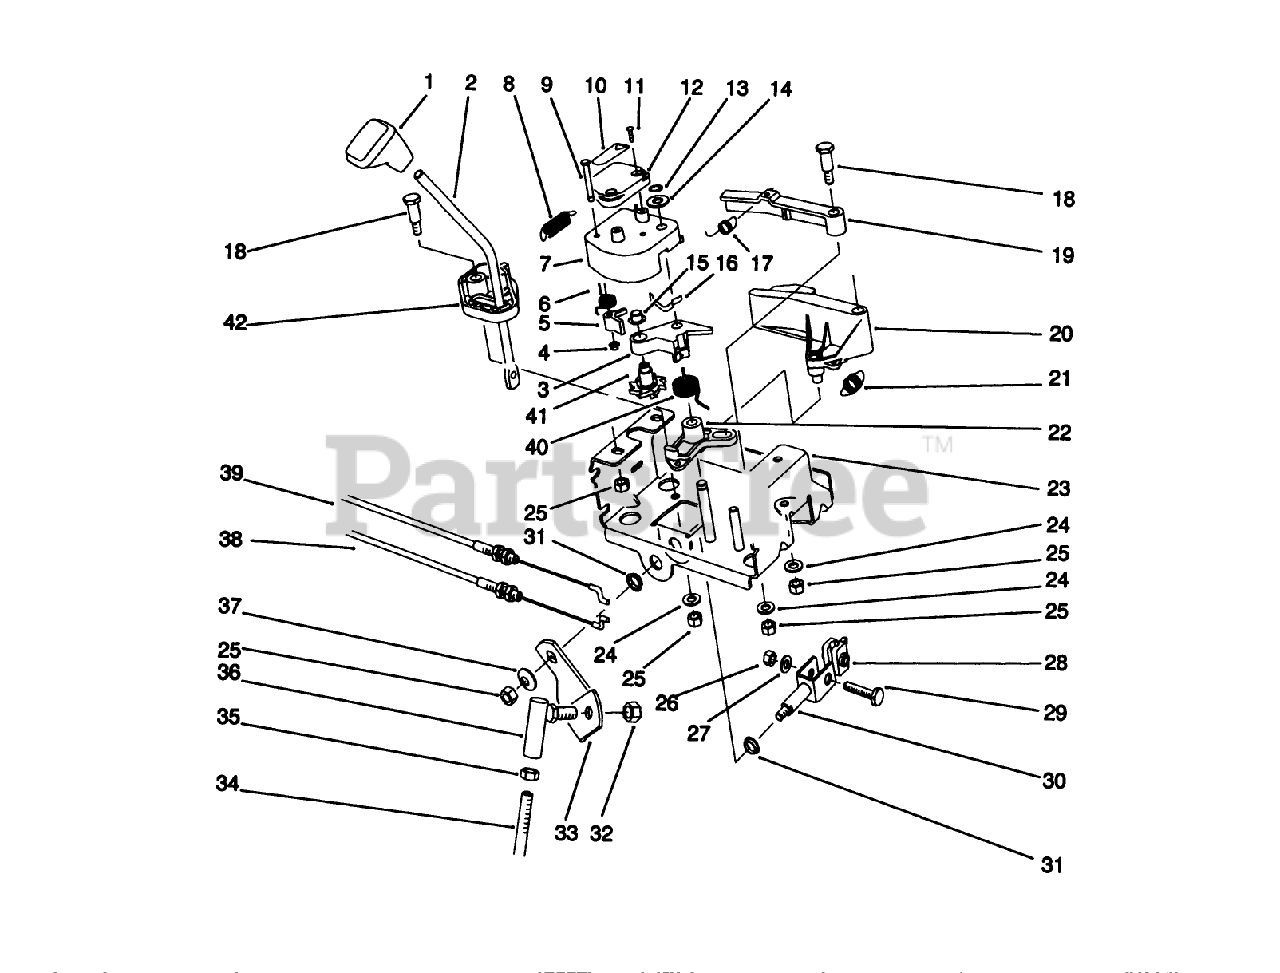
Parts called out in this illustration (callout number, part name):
1	KNOB-SHIFT
2	ROD-SHIFT
3	LEVER-WHEEL, INDEX
4	NUT-PUSH
5	TANG-INDEX
6	SPRING-TORSION
7	LEVER LATCH
8	SPRING-EXTENSION
9	PIN-TANG
10	DECAL
11	SCREW-PPH
12	COVER-LATCH
13	RING-RETAINING
14	WASHER-THRUST
15	NUT-PUSH
17	SPRING-EXTENSION
18	SCREW-SHOULDER
19	LEVER-LOCKOUT
20	LEVER-REVERSE
21	SPRING-EXTENSION
22	LEVER-REVERSE, SWITCH
24	WASHER-PLAIN
25	NUT-LOCK, NI
26	NUT-LOCK, NI
27	WASHER-FLAT
28	RETAINER-ROD, SHIFT
29	CAPSCREW
31	BUSHING
33	BRACKET-SHIFT
34	ROD-BENT SHIFT, LOWER
35	NUT-HJ
37	WASHER-BELLEVILLE
38	CABLE-GEARBOX
39	CABLE-ARM, LATCH
40	SPRING-TORSION
41	WHEEL-INDEX
42	BASE-LOCKOUT
